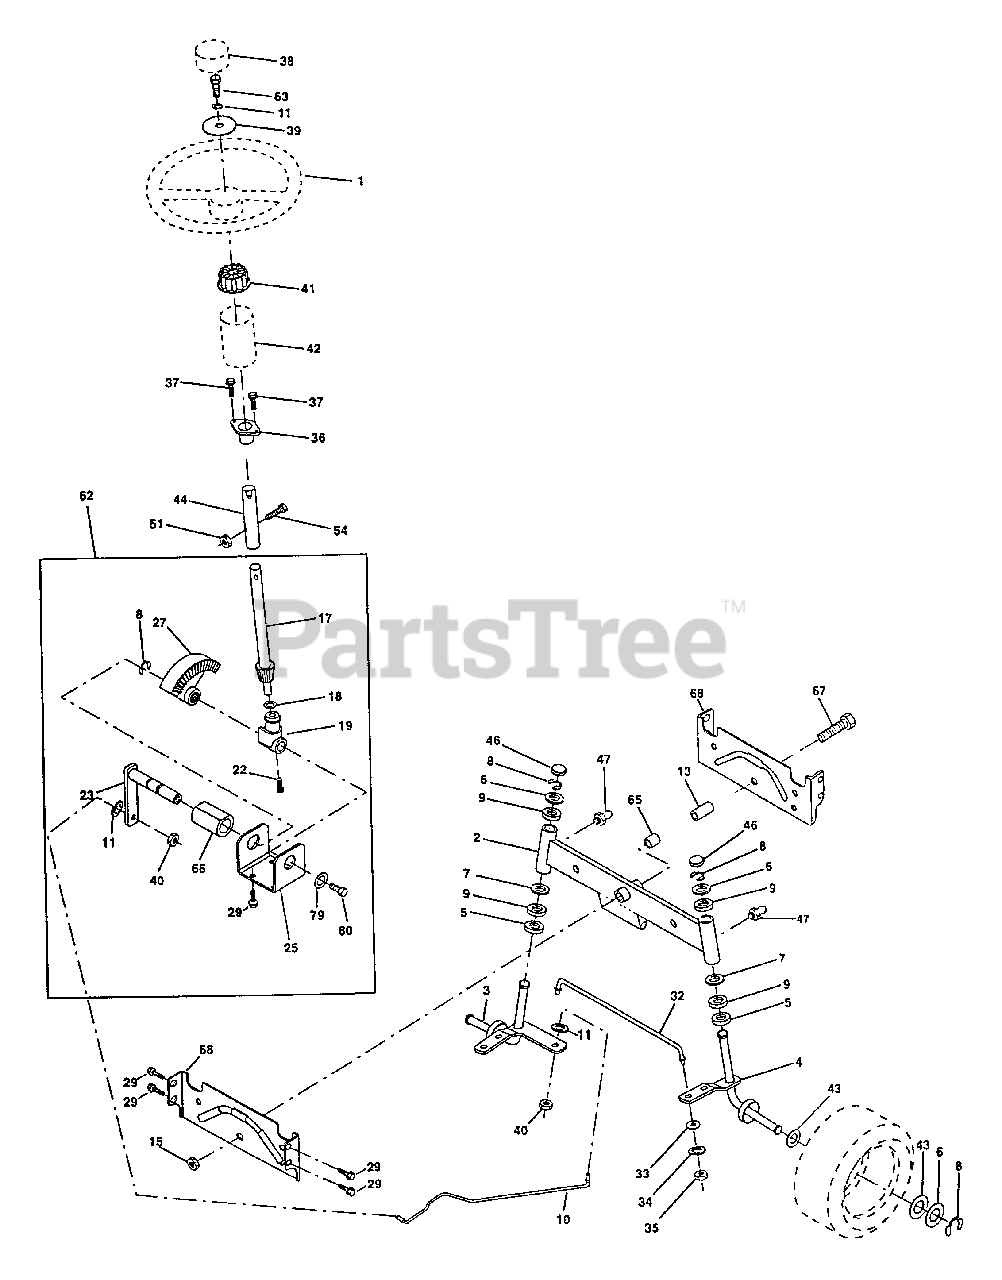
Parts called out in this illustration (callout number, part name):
1	Wheel Steering (AYP part number)
2	Axle Asm Stmp Dropped STLT (AYP part number)
3	Spindle Asm LH
4	Spindle Asm RH
5	Bearing Race Thrust Harden
6	Washer 25/32 X 1-5/8 X 16 Ga
7	Washer 27/32 X 1-1/4 X 16 Ga
8	Ring Klip #t5304-75
9	Bearing Col Strg Blk
10	Link Drag Extended Stamped
11	Washer Lock Hvy Hlcl Spr 3/8
13	Bearing Axle STLT/GT
15	Nut Lock Flange 5/8-11 Unc
17	Shaft Asm Strg
18	Washer Thrust 515x 750x 033
19	Support Shaft
22	Screw Hex Wsh Hd Torx
23	Shaft Asm Pittman
25	Bracket Steering
27	Gear Sector
29	Screw Thdrol 3/8-16x3/4 Ty-tt
32	Rod Tie Ball J Adj VGT (AYP part number)
33	Washer 11/32 x 3/4 x 16 Ga.
34	Washer Lock Hvy Hlcl Spr 5/16
35	Locknut 5/16-24 Unf 3847
36	Bushing Strg (AYP part number)
37	Screw
38	Insert Cap Strg Wh Au
39	Washer 13/32 X 2-3/8 X 8 Ga
40	Lock nut
41	Adaptor Wheel Strg
42	Boot Steering Dash
43	Washer 25/32 X 1 1/4 X 16 Ga
44	Extension Steering Shaft LR/LT (AYP part number)
46	Cap Spindle Fr Top Blk
47	Fitting Grease
51	Nut Lock Hex w/ins 5/16-18
54	Bolt Fin Hex 5/16-18 Unc x 1-1/4
62	Kit, Steering Assembly Svc
63	Bolt Fin Hex 3/8-16unc x 1 Gr. 5
65	Spacer Axle
66	Bearing Arm Pittman
67	Bolt, Fin Hex 5/8-11 UNC x 2-3/4
68	Axle, Brace
79	Washer 13/32 x 1-1/4 x 12 Ga.
80	Bolt Hex Nylon 3/8-16 x 3/4
